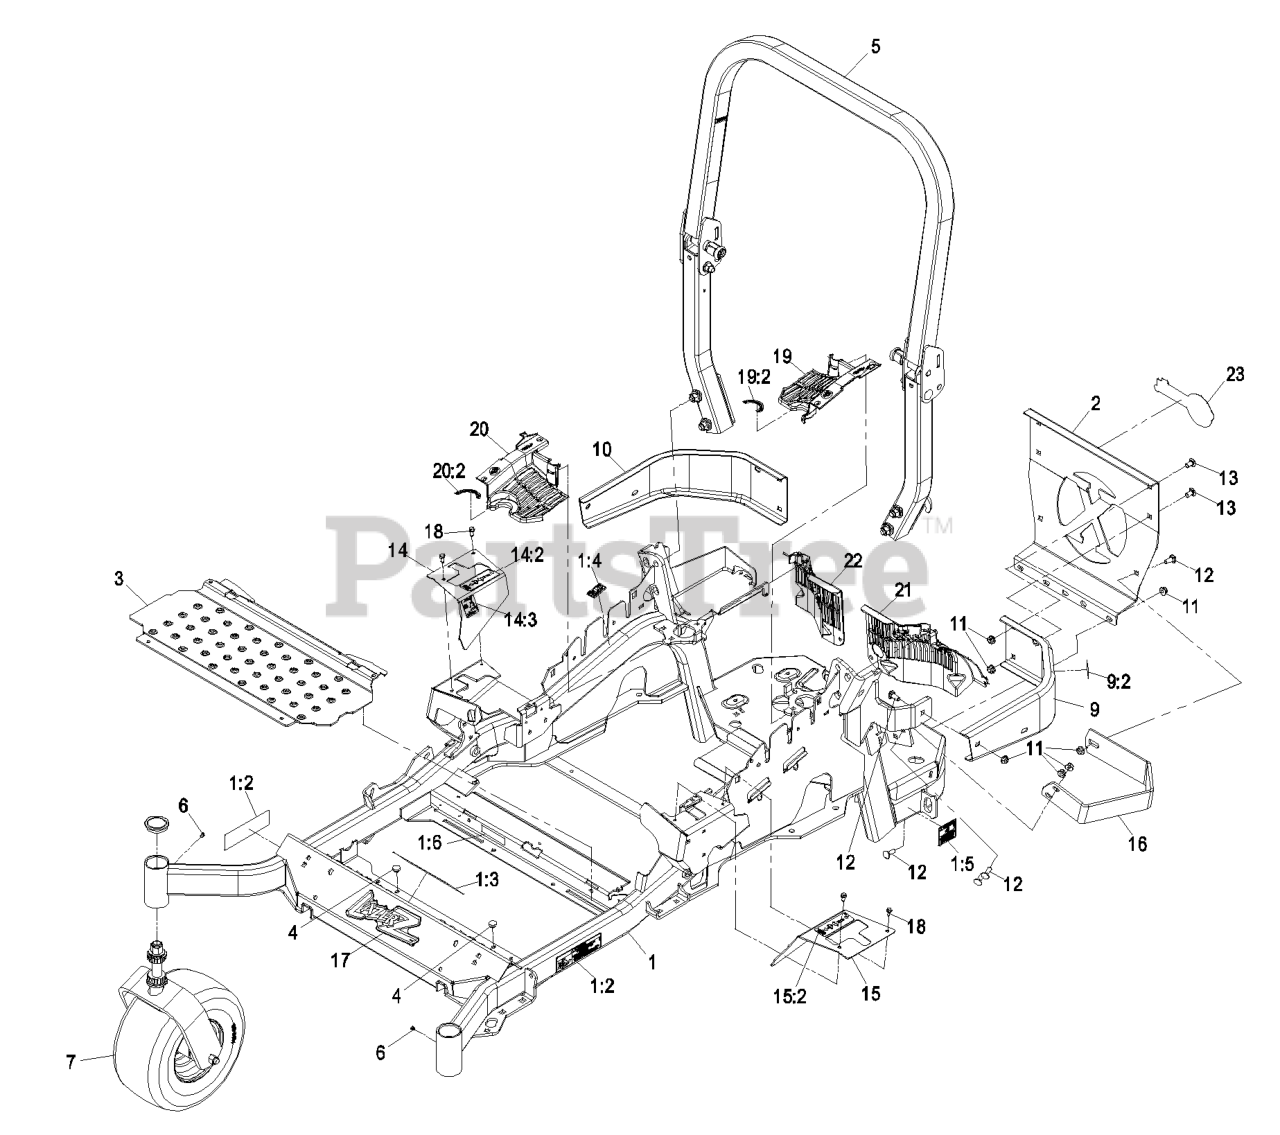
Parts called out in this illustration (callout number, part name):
1	MAIN FRAME ASM
1:2	DECAL-WARNING
1:3	DECAL-WARNING
1:4	DECAL-CAUTION
1:5	DECAL-BELT DRIVE
1:6	DECAL-ARRESTER, SPARK
2	PLATE,REAR GUARD
5	ASM,ROPS SERVICE EXMARK
7	Asm, Caster Wheel
9	LH BUMPER ASM
9:2	DECAL-CAUTION
10	BUMPER-RH
11	NUT-HF, NI
12	SCREW-CARR
13	SCREW-CARR
14:2	DECAL-MOTION CONTROL
15	LH MOTION CONTROL COVER ASM
15:2	DECAL-MOTION CONTROL
17	DECAL,LAZER MODEL
18	SCREW-HWH
19	LH HYDRO GUARD ASM
19:2	DECAL-HYDRO OIL
20	RH HYDRO GUARD ASM
20:2	DECAL-HYDRO OIL
21	GUARD-HYDRO REAR, LH TRIM
22	GUARD-HYDRO, REAR (RH)
